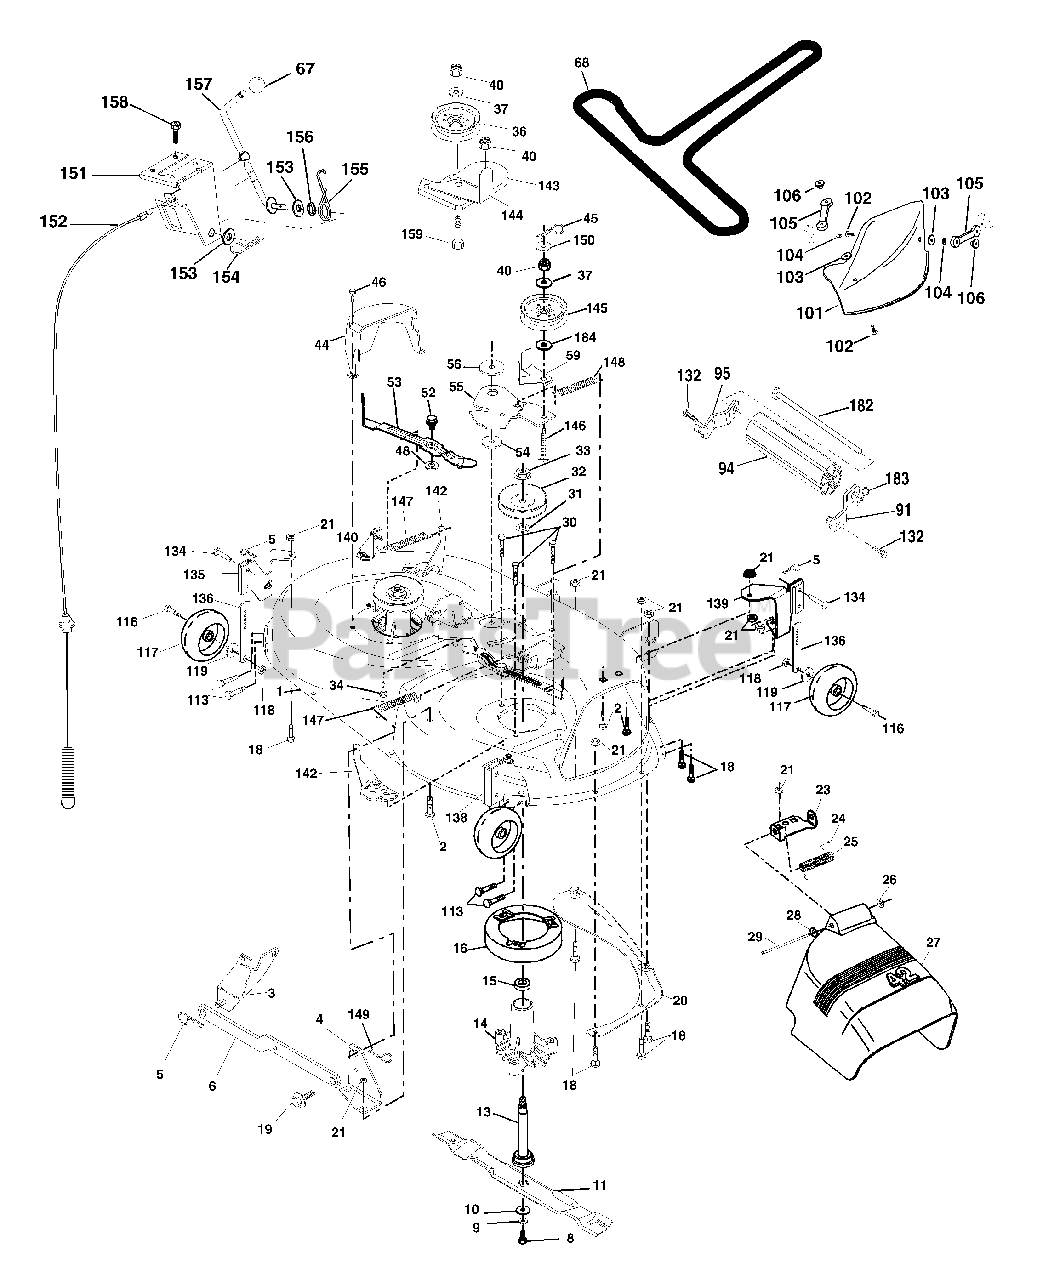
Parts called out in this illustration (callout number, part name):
1	Mower Deck Assembly, 42"
2	Bolt
3	Bracket Asm Fr. Sway Bar 3/42
4	Bracket Asm Deck 42" Sway Bar
5	Retainer Spring
6	Bar Sway Deck
8	Bolt 3/8-24 x 25 Grade 8 patched
9	Washer, Lock
10	Washer, Hardened
11	Blade, Mulching 42" Std
11	Blade Mulching 42" Premium
11	Blade Mower 42" Hi-Lift
13	Shaft Assembly, Mandrel, Vented
14	Housing, Mandrel, Vented
15	Bearing, Ball, Mandrel
16	Stripper, Mandrel Deck
18	Bolt, Carriage 5/16-18 x 5/8
19	Bolt, Shoulder
20	Baffle, Vortex
21	Nut
23	Bracket, Deflector Mower 42"
24	Cap, Sleeve 80 x 112 Blk Mower
25	Spring, Torsion, Deflector 2 52
26	Nut, Push Phos & Oil
27	Shield, Deflector 42" Blk
28	Washer 11/32 x 5/8 x 16 Gauge
29	Rod, Hinge 42" 6 75 W/G
30	Screw Thdrol
31	Washer, Spacer Mower Vented
32	Pulley, Mandrel
33	Nut, Toplock
34	Bolt
36	Pulley, Idler, Flat
37	Washer 13/32 x 13/16 x 16 Gauge
40	Nut
44	Guard, Mandrel, LH
45	Retainer
46	Screw, Thdrol 1/4-20 x 5/8 T
48	Washer, Hardened
52	Bolt, Shoulder 5/16-18 UNC
53	Arm Assembly, Pad, Brake
54	Washer, Hardened
55	Arm, Idler
56	Spacer, Retainer
59	Guard TUV Idler
67	Knob Round
68	V-Belt, 42" Mower
91	Bracket Asm Noseroller LH
94	Roller Nose 38 & 42
95	Bracket Asm Noseroller RH
101	Mulcher Cover
102	Screw, Pan Hd Phillip 10-24 x 5/8
103	Washer, Flat
104	Washer, Lock
105	Latch Assembly
106	Nut, Weld
113	Screw 5/16-18 x 3/4
116	Bolt, Shoulder
117	Wheel, Gauge
118	Nut Centerlock 3/8-16
119	Washer 3/8 x 7/8 x 14 Ga.
132	Screw 3/8-16 x .75
134	Pin Head Rivet
135	Bracket Asm. Whl Ga. R LH
136	Bar Adjusting Gauge Wheel
138	Bracket Asm Whl Ga. R RH
139	Bracket Asm. Whl Ga. F RH
140	Bracket Asm Whl Ga. F LH
142	Arm Spring Brake Mower
143	Bracket Arm Idler 42"
144	Keeper Belt 42" Clutch Cable
145	Pulley Idler Flat
146	Bolt Carriage Idler
147	Spring Extension
148	Spring Return Idler
149	Retainer Spring Yellow
150	Washer 9/32 x 3/4 x 16 Ga.
151	Bracket Clutch Cable
152	Clutch Cable 42"
153	Washer Flat 3/8" Type B
154	Spring Retainer
155	Spring Retention LVR CLTCH CAB
156	Spacer Clutch Cable
157	Rod Clutch Cable 3/8"
158	Screw Hex Thd Cut 1/4-20 x 1/2
159	Bolt Rdhd Sqn 3/8-16 UNC x 1-3/4
182	Rod Roller Nose
183	Retainer Spring
184	Washer 13/32 x 7/8 x 10 Ga.
